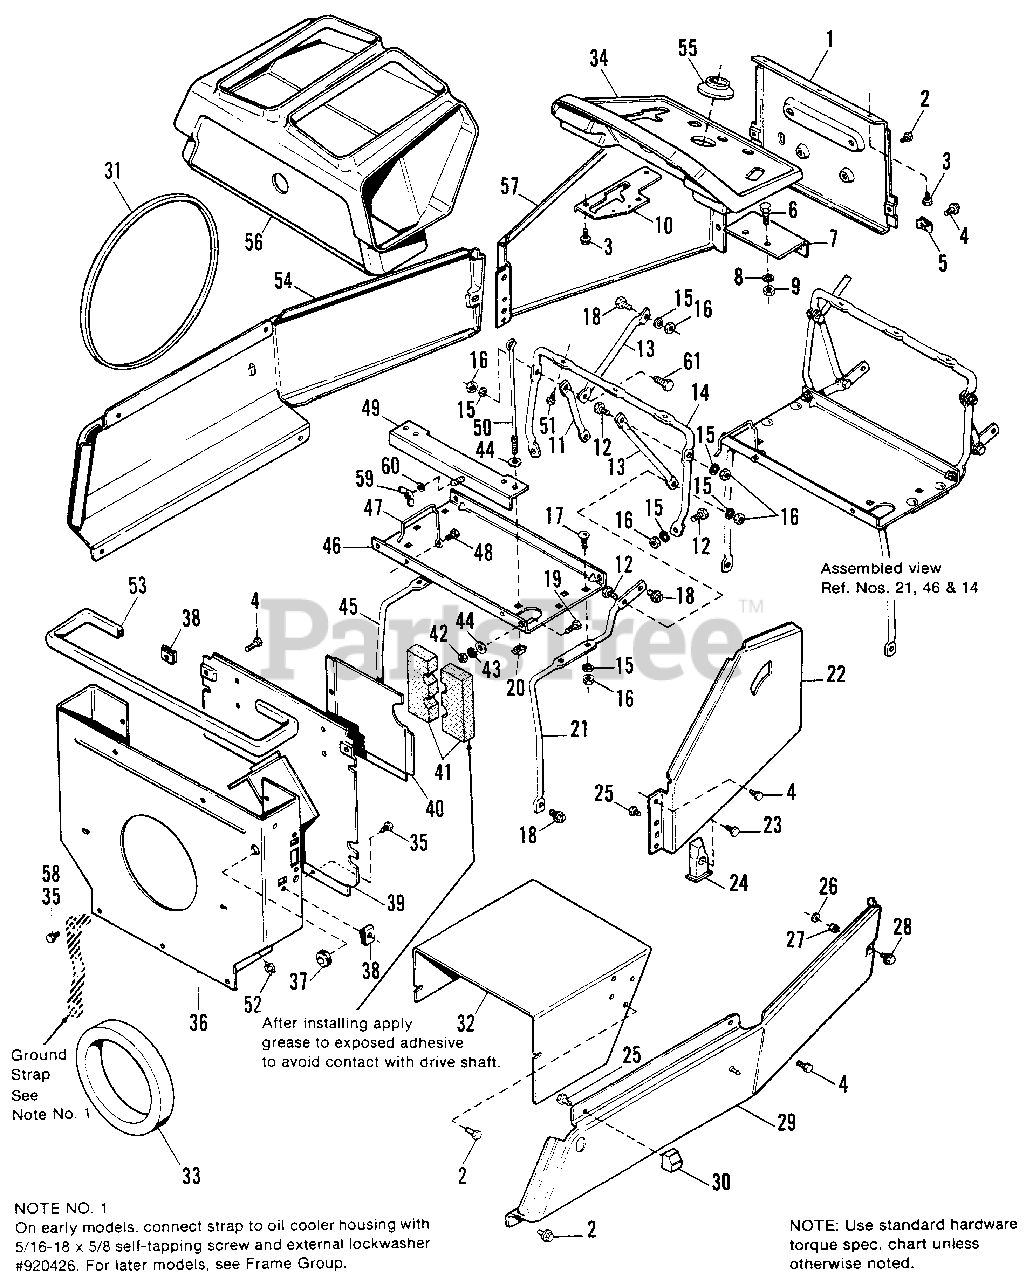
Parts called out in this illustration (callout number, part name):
1	PANEL, Rear Dash
2	SCREW, Hex, Taptite, 1/4-20 x 5/8
3	SCREW, Hex, Plastite, 1/4-10 x 5/8 (Qty. 5 on 1691018)
4	SCREW, Hex, Type "AB", 1/4-14 x 5/8
5	SPEED NUT, "J" Type, 14A
6	CAPSCREW, Hex Hd., 3/8-16 x 1
7	BRACKET, Mounting, Dash Panel, Rear
8	LOCKWASHER, 3/8
9	NUT, Hex, 3/8-16
10	PLATE, Speed Control Lever
11	BRACE, Dash Cap Support, R.H.
12	CAPSCREW, Hex Hd., 5/16-18 x 1
13	BRACE, Dash Cap Support, L.H.
14	SUPPORT, Dash Cap
15	LOCKWASHER, 5/16
16	NUT, Hex, 5/16-18
17	BOLT, Carriage, 5/16-18 x 7/8
18	CAPSCREW, Hex, Taptite, 5/16-18 x 3/4
19	CAPSCREW, Hex Hd., 1/4-20 x 3/4
20	SPEED NUT, Retaining, 1/4-20
21	SUPPORT, Battery Tray, L.H.
22	DASH PANEL, Upper, L.H.
23	SCREW, Hex, 1/4 x 1
24	GUIDE, Spacer, Hood
25	SCREW, Hex, Plastite, #10-14 x 1/2
26	PUSHNUT, .250
27	SPACER, Side Panel
28	SCREW, Hex, Taptite, 1/4-20 x 1
29	PANEL ASSY., L.H.
30	SPACER, Hood/Side Panel
31	STRAP, Plenum
32	COVER, Tunnel (1691017 only)
32	COVER, Tunnel (1691018 only)
33	SEAL, Engine, Bulkhead
35	SCREW, Hex, Taptite, 5/16-18 x 3/4
37	GROMMET, 1/2" ID
38	SPEED NUT, "U" Type, 14A
39	PANEL ASSY., Bulkhead
40	PANEL, Clean Out
41	SEAL, Drive Shaft
42	NUT, Hex, 1/4-20
43	LOCKWASHER, 1/4
44	WASHER, Plain, 1/4
45	SUPPORT, Battery Tray, R.H.
46	TRAY, Battery
47	GUIDE, Plenum
48	SCREW, Hex, Taptite, 1/4-20 x 1/2
49	HOLD DOWN, Battery
50	ROD, Battery Hold Down
51	SCREW, Hex, Plastite, 1/4-10 x 3/4
52	CLIP, Routing, Snap-In
53	SEAL, Plenum, Bulkhead
54	LOWER PANEL ASSY., R.H.
55	BOOT, Steering Stem
56	PLENUM, Air Induction
57	DASH PANEL, Upper, R.H.
58	SCREW, Hex Taptite, 5/16-18 x 5/8
59	NUT, Wing, 1/4-20
60	WASHER, 1/4
61	CAPSCREW, Hex, 5/16-18 x 1-1/4
